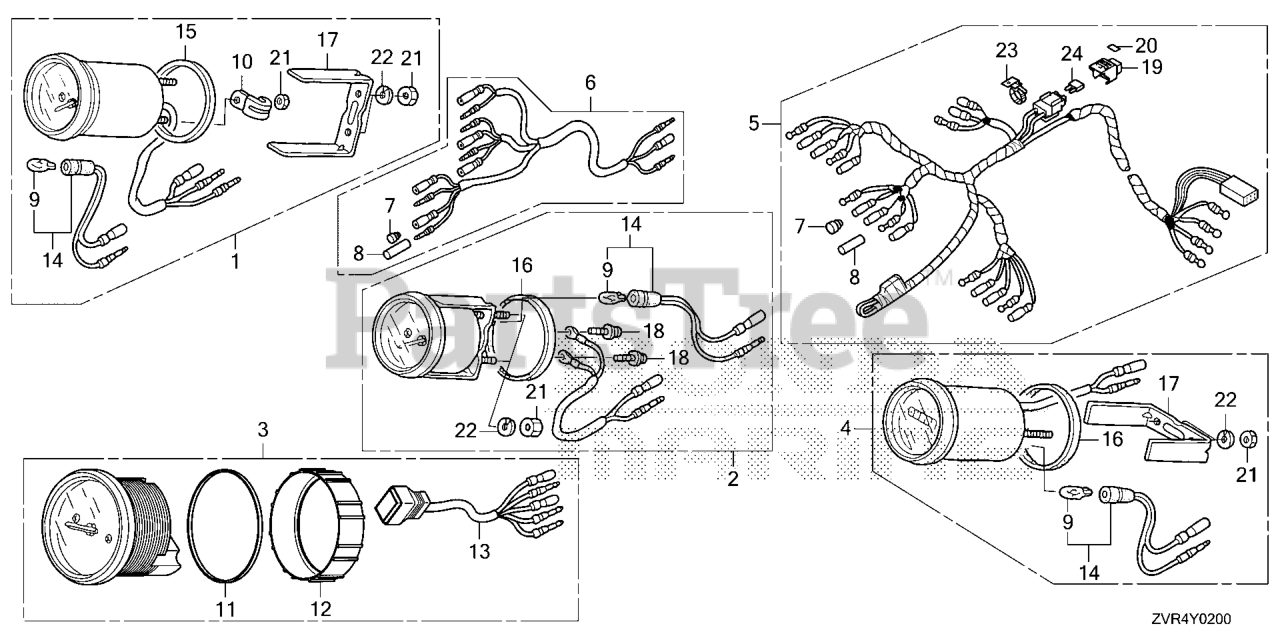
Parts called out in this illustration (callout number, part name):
1	METER KIT, TRIM (WHITE)
1	METER KIT, TRIM (B) (BLACK)
2	METER KIT, VOLT (WHITE)
2	METER KIT, VOLT *NHA85* (B) (BLACK)
3	TACHO METER KIT
4	METER KIT, HOUR (WHITE) (NA USE ALT:39700-ZW5-000ZA)
4	METER KIT, HOUR (B) (NA USE ALT:39700-ZW5-000ZA)
5	HARNESS ASSY., METER (A)
6	HARNESS ASSY., METER (B)
7	PLUG, CONNECTOR (INNER) (TROLLING CONTROL)
8	PLUG, CONNECTOR (OUTER) (ENGINE NO.)
9	BULB, WEDGE BASE (12V1.7W) (TOSHIBA)
10	CLAMP
11	CUSHION RUBBER
12	RING
13	WIRE ASSY.
14	SOCKET
15	GASKET (TO 1015209) (FROM 1015210)
16	GASKET
17	BRACKET (TO 1015209) (FROM 1015210)
18	SCREW-WASHER (3X22)
19	COVER ASSY., FUSE
20	LABEL, FUSE (10A)
21	NUT, HEX. (4MM)
22	WASHER, SPRING (4MM)
23	HOLDER, CONNECTOR (128.6MM) (NATURAL)
24	FUSE, MINI (10A)
